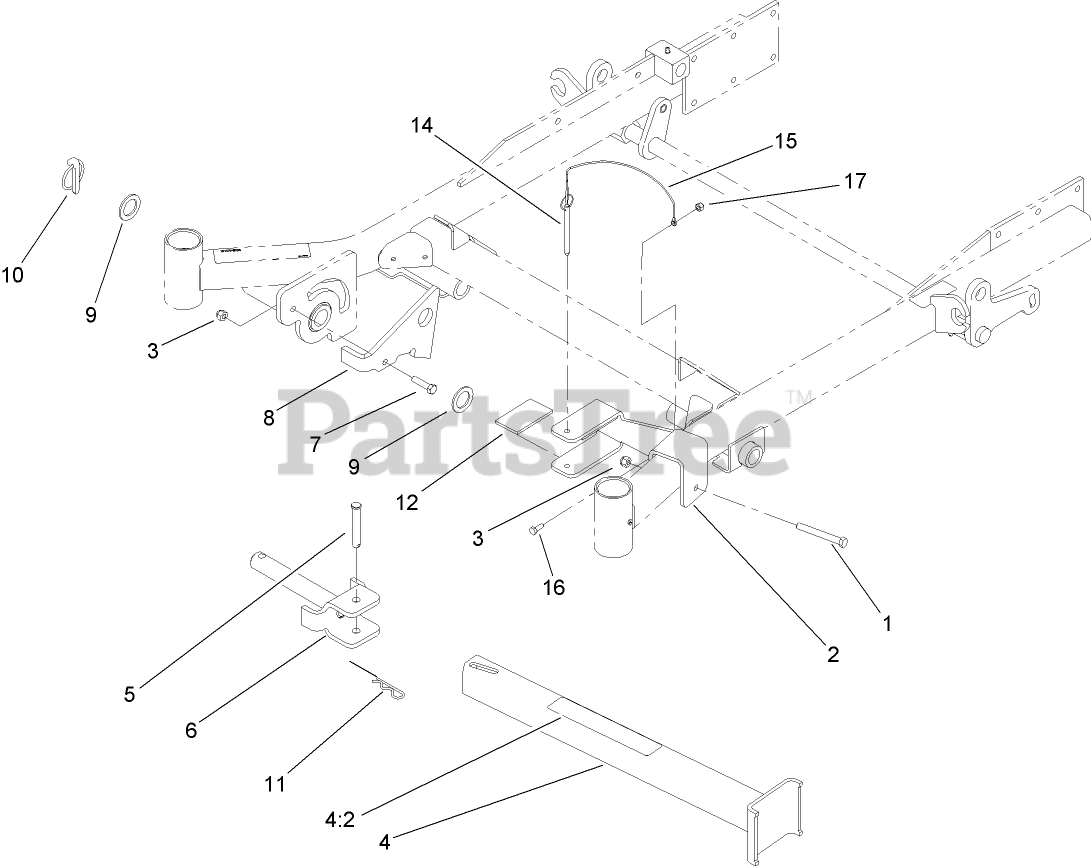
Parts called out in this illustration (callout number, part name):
1	SCREW-HH
2	BRACKET-CRADLE
3	NUT-LOCK, NI
4	Leg ASM
4:2	DECAL-Z STAND
5	PIN-CLEVIS
6	PIN-PIVOT
7	SCREW-HH
8	BRACKET-LATCH
9	WASHER-THRUST
10	PIN-LYNCH
11	PIN-HAIR
12	Cushion-Rubber
14	PIN-HITCH, COTTERLESS
15	LANYARD-NYLON
16	SCREW-HH
17	NUT-LOCK, NI
